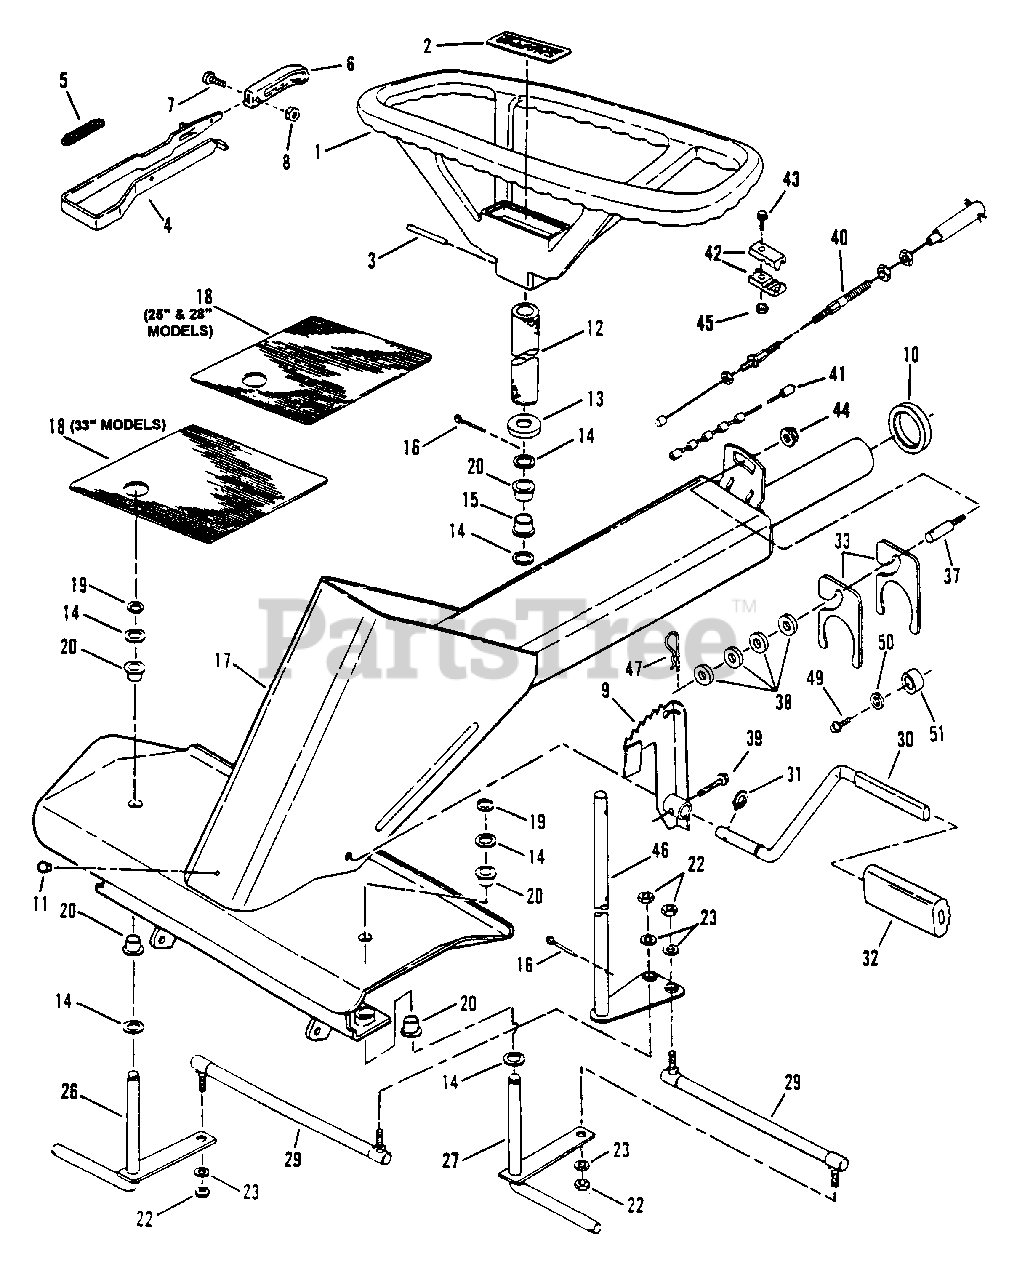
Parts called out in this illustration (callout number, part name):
1	ASSEMBLY, Steering Wheel
2	DECAL, Snapper
3	PIN, 1/4 x 1 1/2" Roll
4	BRACKET, Clutch/Brake
5	SPRING
6	KNOB
7	SCREW, #8-32 x 3/8" Cross Recess
8	NUT, #8-32 Hex
9	ARM, Clutch/Brake
10	SPACER, Main Tube
11	PLUG
12	COVER, Steering Shaft (Foam)
13	COVER
14	WASHER, 3/4 Flat
15	BUSHING, 3/4" Steering Shaft
16	PIN, 3/16 x 1-1/2" Cotter
17	FRAME, Front
18	PAD, Foot (Right Side)
19	RING, Retaining
20	BEARING
22	NUT, 5/16-24 Hex
23	WASHER, 5/16 Split Lock
26	PIN, Wide King (Right Side)
27	PIN, Wide King (Left Side)
29	TIE-ROD
30	PEDAL, Clutch/Brake
31	RING, 5/8" External Retaining
32	PAD, Clutch/Brake Pedal
33	SPACER, Pivot
37	STUD, 3/8-24 x 5/8" Shoulder
38	SPACER
39	SCREW, 5/16-18 x 1 1/4" Self-Tapping
40	CABLE, Brake
41	CABLE, Clutch
42	UNION, Cable
43	BOLT, 1/4-20 x 3/4" Hex Flange Lock
44	NUT, 3/8-16 Hex Nyloc
45	NUT, 1/4-20 Hex Center Lock
46	SHAFT, Steering (Wide Front End)
47	PIN, 1/8 x 2 9/16 Hair
49	SCREW, 3/8-16 x 5/8" Self Tapping
50	WASHER, 3/8" Flat
51	SPACER, .39 x .625 x .19
